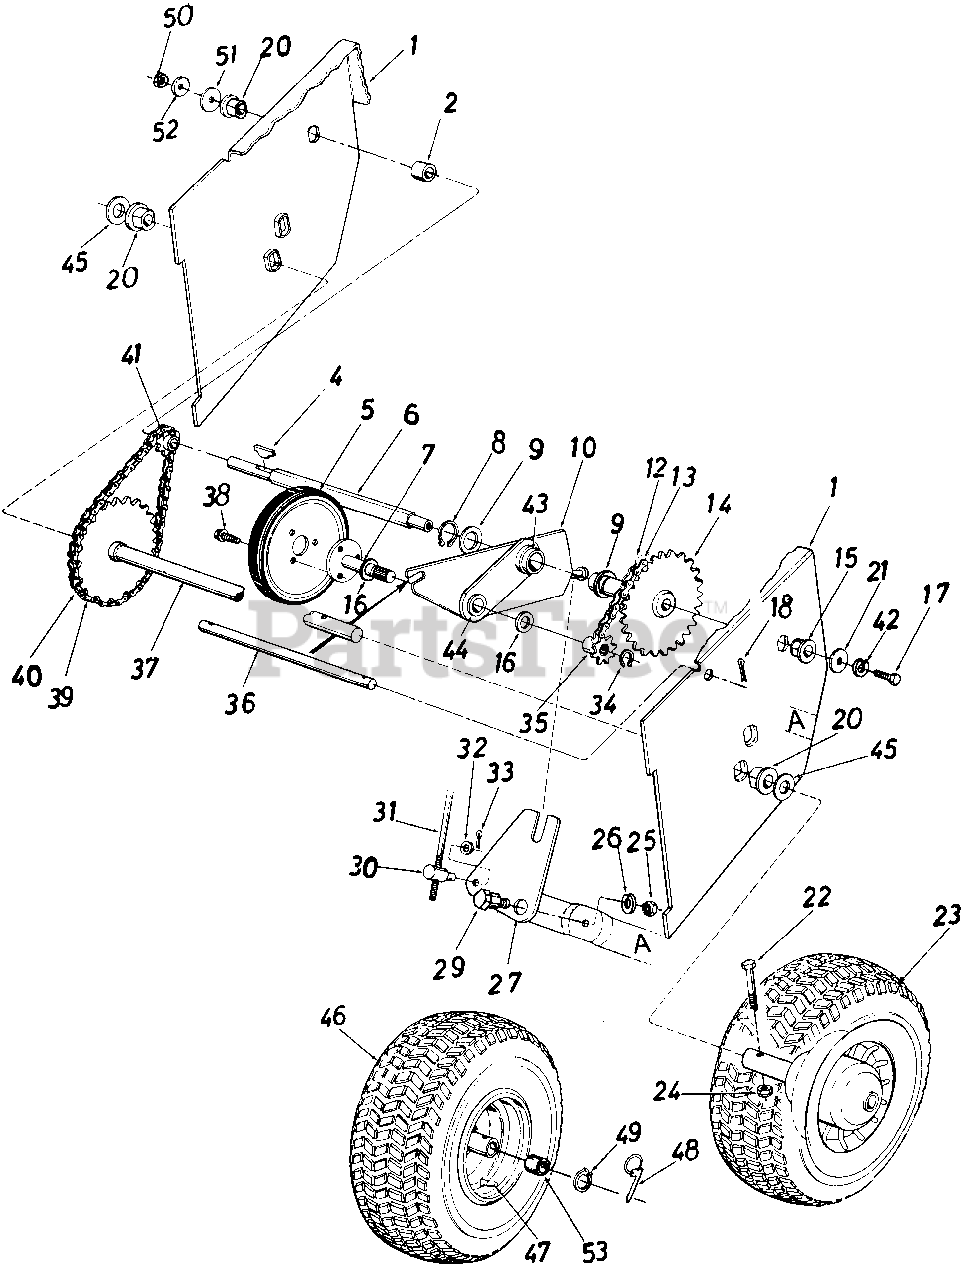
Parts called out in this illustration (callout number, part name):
1	Frame Ass'y.
2	Spacer. 50" I.D. x .75" O.D. x.78" Lg.
4	#4 Hi-Pro Key 3/32 x 518" Dia.
5	Friction Wheel Ass'y.
6	Hex Shaft
7	Friction Wheel Mounting Plate Ass'y.
8	Snap Ring 1.00" Dia. Shaft
9	Fl-Wash 1.00" 1.63" O.D. x .03
10	Sliding Bracket Ass'y.
12	#41 Chain 1/2" Pitch x 35 Links
13	Master Link for #41 Chain
14	32 Teeth Sprocket Ass'y.
15	Hex Flange Brg. .630" I.D.
16	Fl-Wash. .62" I.D. x 1.00" O.D. x .06
17	Hex Lock Bolt 5/16-18 x .62" Lg.
18	Cotter Pin 3132" Dia. x .75" Lg.*
20	Flange Brg. w/Flats .755" I . D.
21	Fl-Wash. .34" I.D. x 1.12" O.D. x .125
22	Hex Bolt 5/16-24 x 1.50" Lg.
23	Wheel Ass'y.
24	Hex Ins. Jam L-Nut 5/16-24 Thd.
25	Hex Jam Nut 3/8-16 Thd.
26	L-Wash. 3/8" I.D.
27	Shifting Linkage Bracket
29	Shld. Bolt .625" Dia. x .170" Lg.
30	Adjustment Ferrule
31	Shifting Rod 5/16" Dia. x 32.50" Lg.
32	Fl-Wash. .34" I.D. x .64" O.D. x .06
33	Cotter Pin 3/32" Dia. x .75" Lg.
34	Snap Ring .562" Dia. Shaft
35	Sprocket 7 Teeth x .50" Pitch
36	Shaft .50" Dia. x 9.50" Lg.
37	28 Teeth Wheel Axle Ass'y.
38	Hex Wash. Hd. Self-Tap Scr. 5/16-24 x .50" Lg.
39	#41 Chain 1/2" Pitch x 43 Links
40	Master Link for #41 Chain
41	8 Teeth Center Sprocket
42	L-Wash. 5/16" I.D.
43	Bearing
44	Bronze Bearing
45	Fl-Wash. .76" I.D. x 1.49 O.D.
46	Wheel Ass'y. Comp. 10.5 x 3.5
46	Wheel Assembly
47	Air Valve
48	Klick Pin
49	Snap Ring .75 Dia.
50	Hex Ins. L-Nut 1/2-20 Thd.
51	Fl-Wash. .53 I.D. x 1.25 O.D. x .10
52	Bell-Wash. .50 I.D. x 1.0 O.D. x .075
53	Sleeve Brg.
